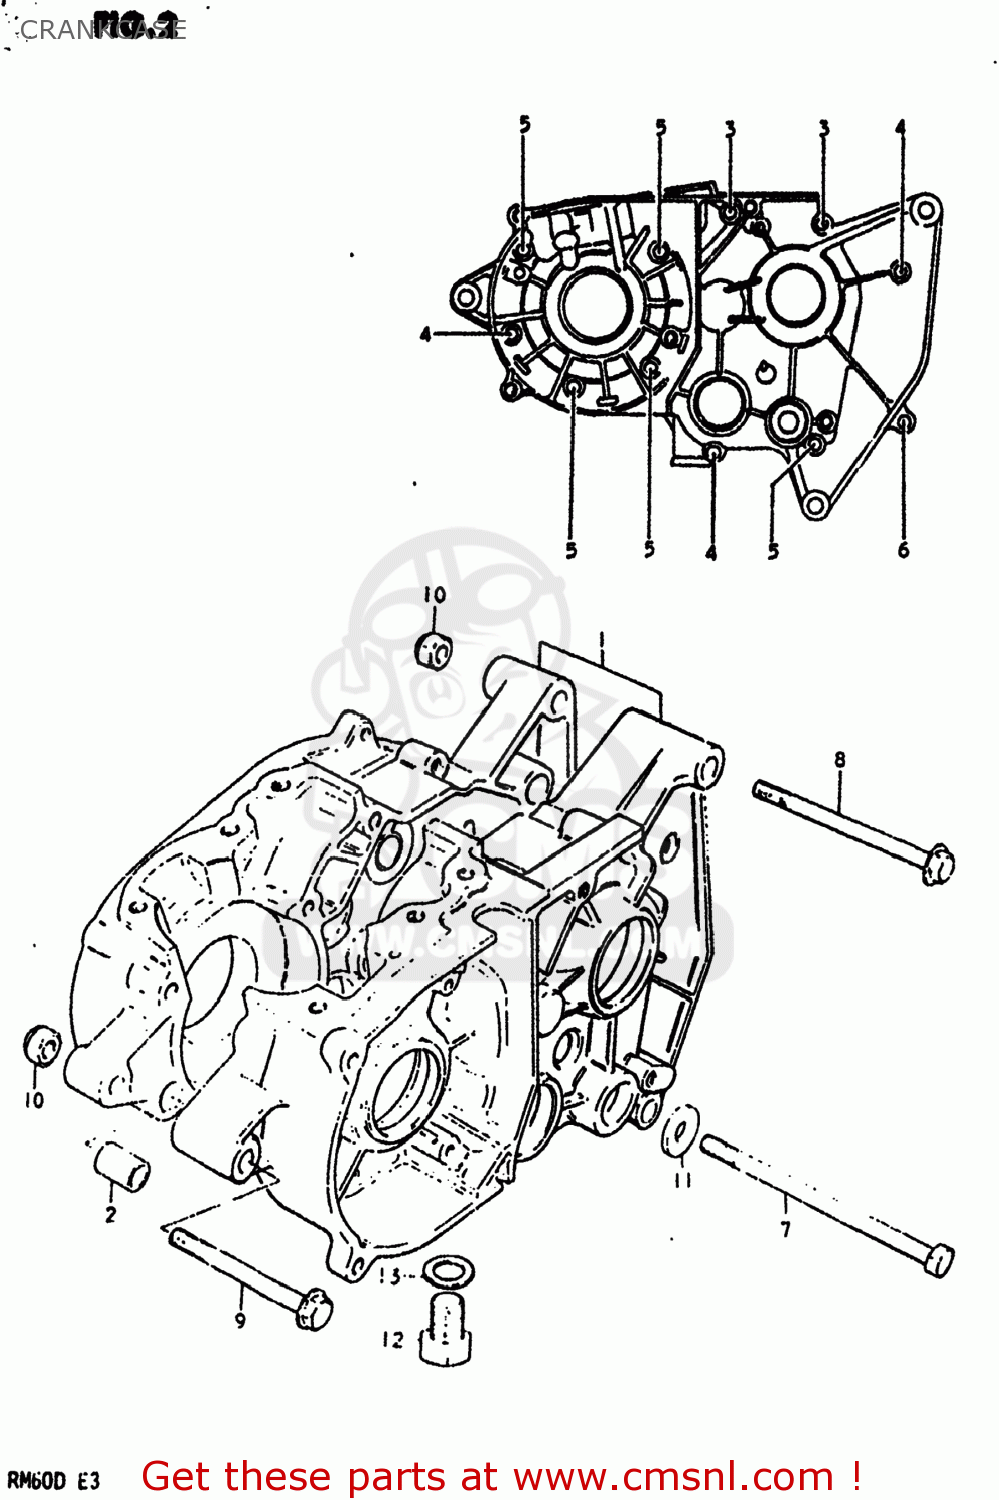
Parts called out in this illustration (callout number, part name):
1	CRANKCASE SET
2	PIN
3	CROSS SCREW (6 X 75)
4	SCREW
5	SCREW (6X35)
6	SCREW
7	BOLT 8X115
8	BOLT
9	BOLT 8X75
10	NUT
11	WASHER
12	BOLT 10X20
13	GASKET(10X14X3.6) (NAS)
